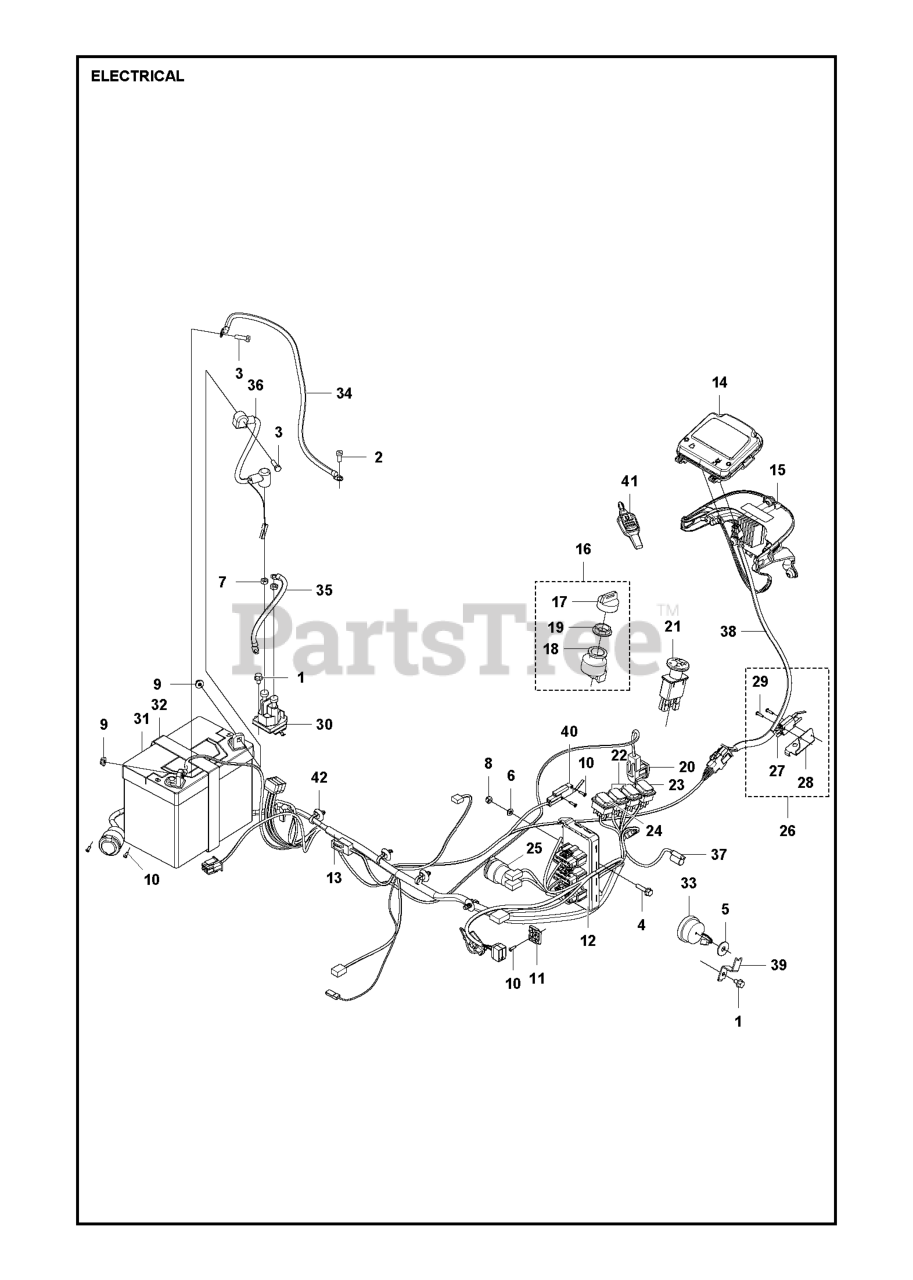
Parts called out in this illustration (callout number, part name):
2	SCREW
3	SCREW EHHM
8	LOCKNUT M6
12	CONTROL.UNIT.RIDE.ON.IRIS.BASE
20	REVERSE SWITCH
21	SWITCH.PTO.8TERMINAL.STD.BLK
27	MICRO SWITCH
30	RELAY
40	MICRO SWITCH
